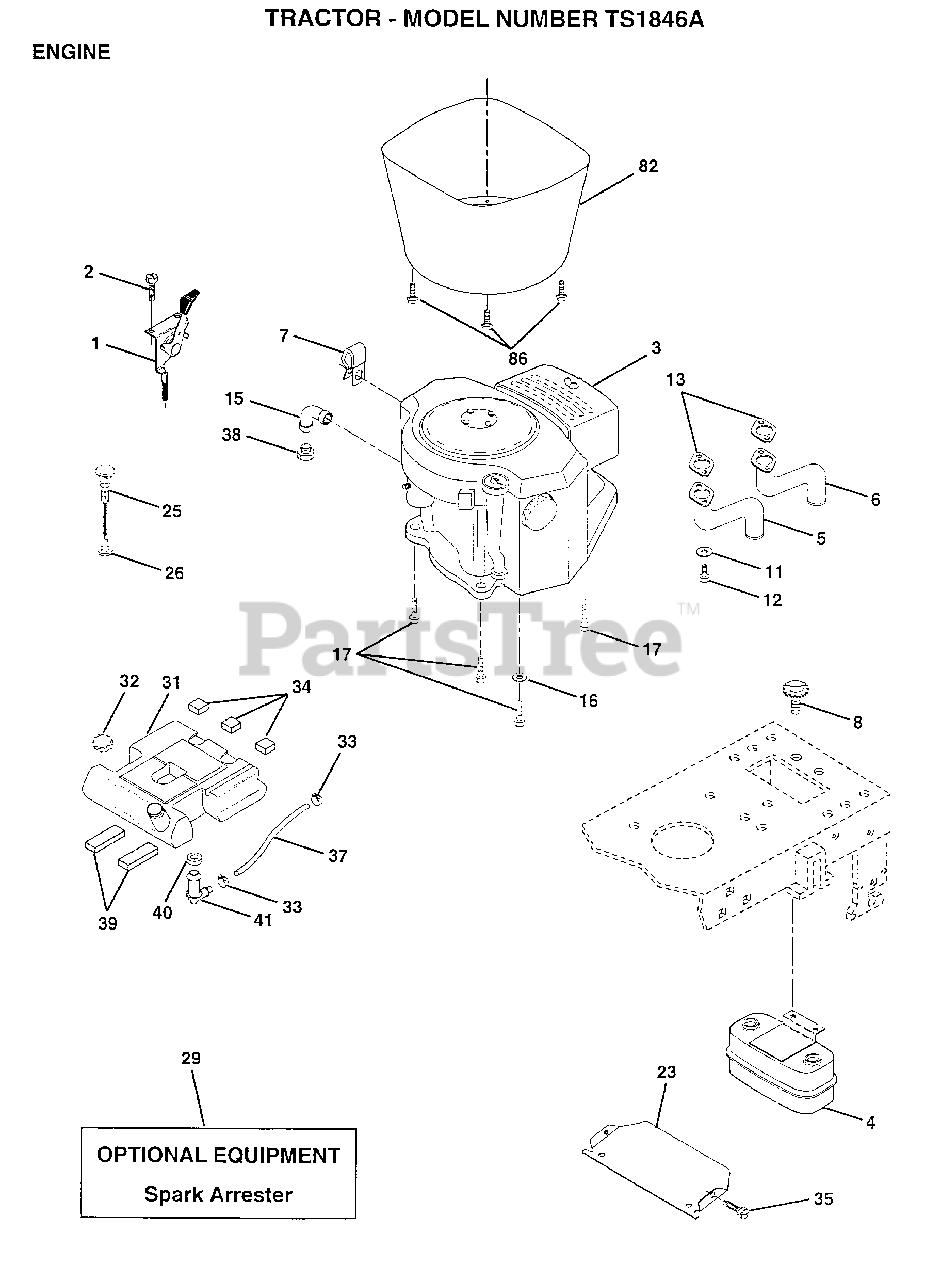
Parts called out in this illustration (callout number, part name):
2	SCREW LT
4	MUFFLER.TW.LOTONE
5	TUBE MANIFOLD LH
6	TUBE MANIFOLD RH
7	CLAMP.TUBE.DBL.EN
8	BOLT.5/16-18.UNC
11	LOCKWASHER
12	SCREW
13	GASKET-MUFFLER )
15	STREET ELBOW LT
16	LOCKWASHER
17	SCREW LT
25	"CONTROL.CHOKE.51"""
26	"NUT,KEPS 3/8-24IM"
31	TANK FUEL REAR
32	CAP ASM FUEL
33	HOSE CLAMP
34	PAD-SPACER LT
35	SCREW
37	FUEL LINE T
38	PLUG T
39	PAD IDLER TI
40	BUSHING OUTLET T
41	STEM.TANK.FUEL
82	DUCT, AIR ONAN
86	"SCREW-TT,10-32 FL"
